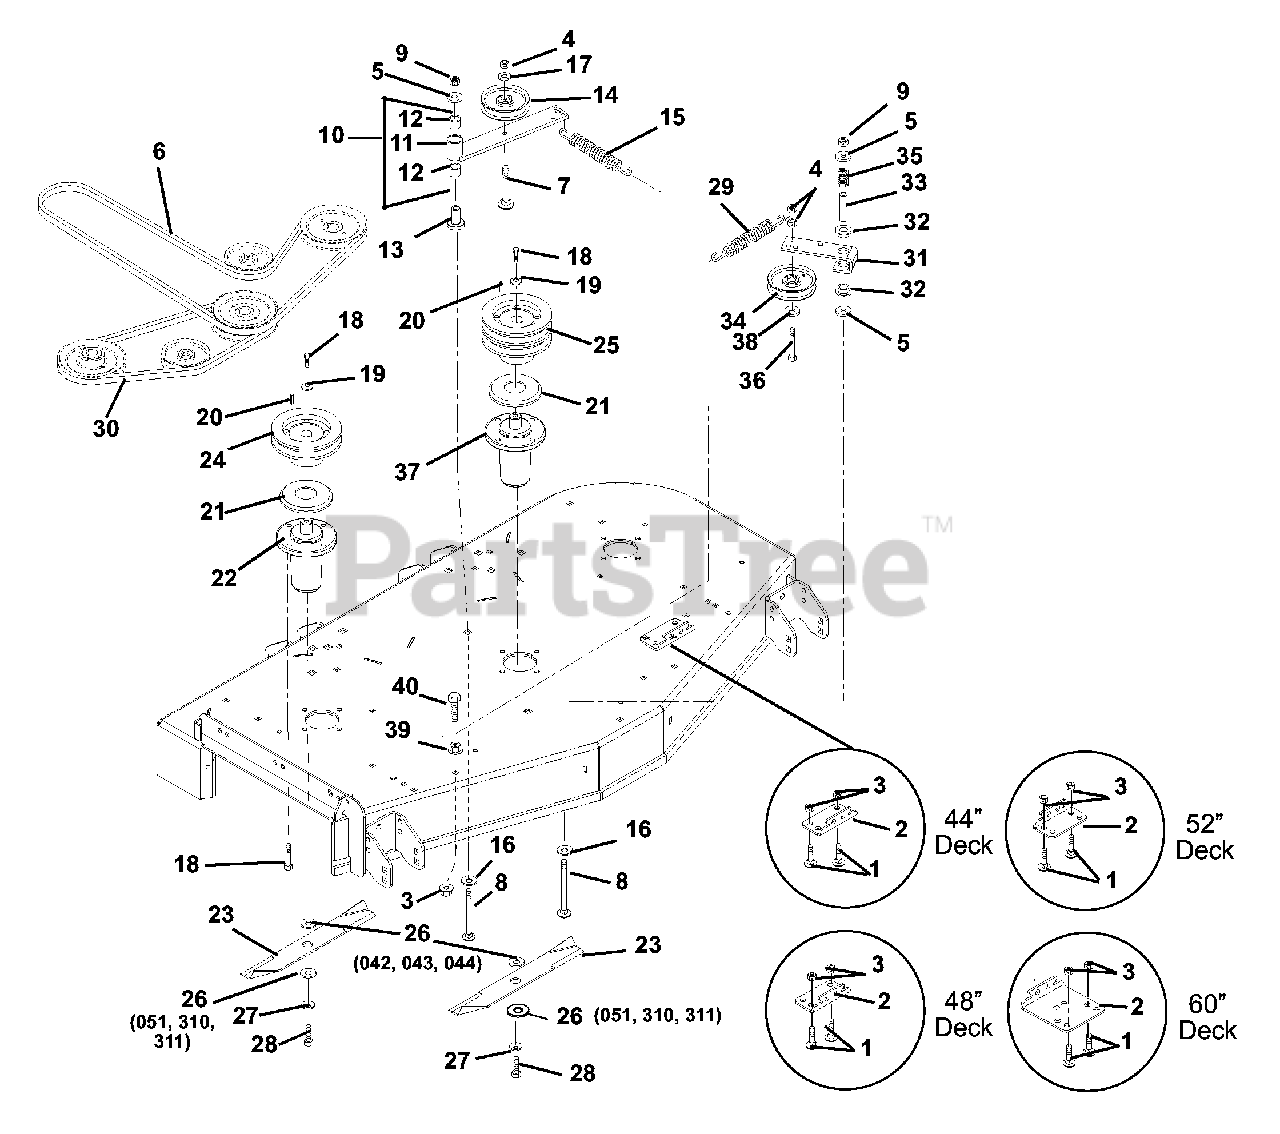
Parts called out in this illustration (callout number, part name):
1	Bolt, Round Head Square Neck .38-16 x .75 Grade 5
2	Bracket, Spring (042, 043, 044, 054, 310, 311)
2	Bracket, Spring (051, 055)
3	Nut, Locking Top Flange .38-16
4	Nut, Locking Center .38-16
5	Washer, Flat Steel .531 x 1.25 x .10
6	V-Belt, B-Section 51.50 x .625 (042, 044, 054, 310)
6	V-Belt, B-Section 55.75 x .625 (051, 055)
6	V-Belt, B-Section 48.80 x .625 (043, 311)
7	Bolt-Round Head Square Neck .38-16 x 2.75 Grade 5
8	Bolt, Round Head Square Neck .50-13 x 3.50 Grade 5
9	Nut, Locking Top Flange .50-13
10	Assembly, Idler Pivot Arm
11	Weldment, Idler Pivot Arm
12	Bearing, 1.00 x 1.12 x .75
13	Bearing, Pedestal Powdered Metal
14	Idler, Flat 4.00 x .38 (2.00 W)
15	Spring, Extension
16	Washer, Flat Steel .755 x 1.375 x .062
17	Washer, Flat Steel .375 x 1.125 x .065
18	Bolt, Hex .38-16 x 1.00 Grade 8
19	Washer, Cupped Serrated .375
20	Key, Square .25 x .25 x 1.00 RC 40-50
21	Slinger, Dust
22	Assembly, Maintenance Free Spindle
23	Blade, Mower (18.00) (044, 054)
23	Blade, Mulching (044, 054)
23	Blade, Mower 60" (051, 055)
23	Blade, Mower 60" Tungsten Mulch (051, 055)
23	Blade, Mower (042, 043)
23	Blade, 32" (16.25) (310, 311)
23	Blade, Mulching (042, 043)
24	Weldment, Spindle Sheave 5.00 (042, 043, 044, 054, 310, 311)
24	Weldment, Spindle Sheave 6.00 (051, 055)
25	Sheave, Double (5.25") (042, 044, 054, 310, 311)
25	Sheave, Double (6.25") (051, 055)
26	Washer, Flat .64 x 1.81 x .250
27	Washer, Bellville .63 x 1.625 x .14
28	Bolt, Hex .62-18 x 1.75 Grade 8
29	Spring, Extension
30	V-Belt, B-Section 19.10 x .672 (044, 054)
30	V-Belt, B-Section 23.94 x .625 (051, 055)
30	V-Belt, 5L-Section 49.97 x .672 (042, 043, 310, 311)
31	Arm, Idler Pivot
32	Bushing, Flange .762 x 1.00 x .58 x 1.48 Nylon
33	Spacer .56 x .75 x 2.44 Steel
34	V-Idler, 4.00 x .38
35	Spring, Compression .085 x .80 x 1.00
36	Bolt, Hex .38-16 x 2.25 Grade 5
37	Spindle Assembly (Center)
38	Washer, Flat Steel .406 x .812 x .065
39	Nut-Flange .375-16
40	Bolt-Hex .38-16 x 3.50 Grade 5
